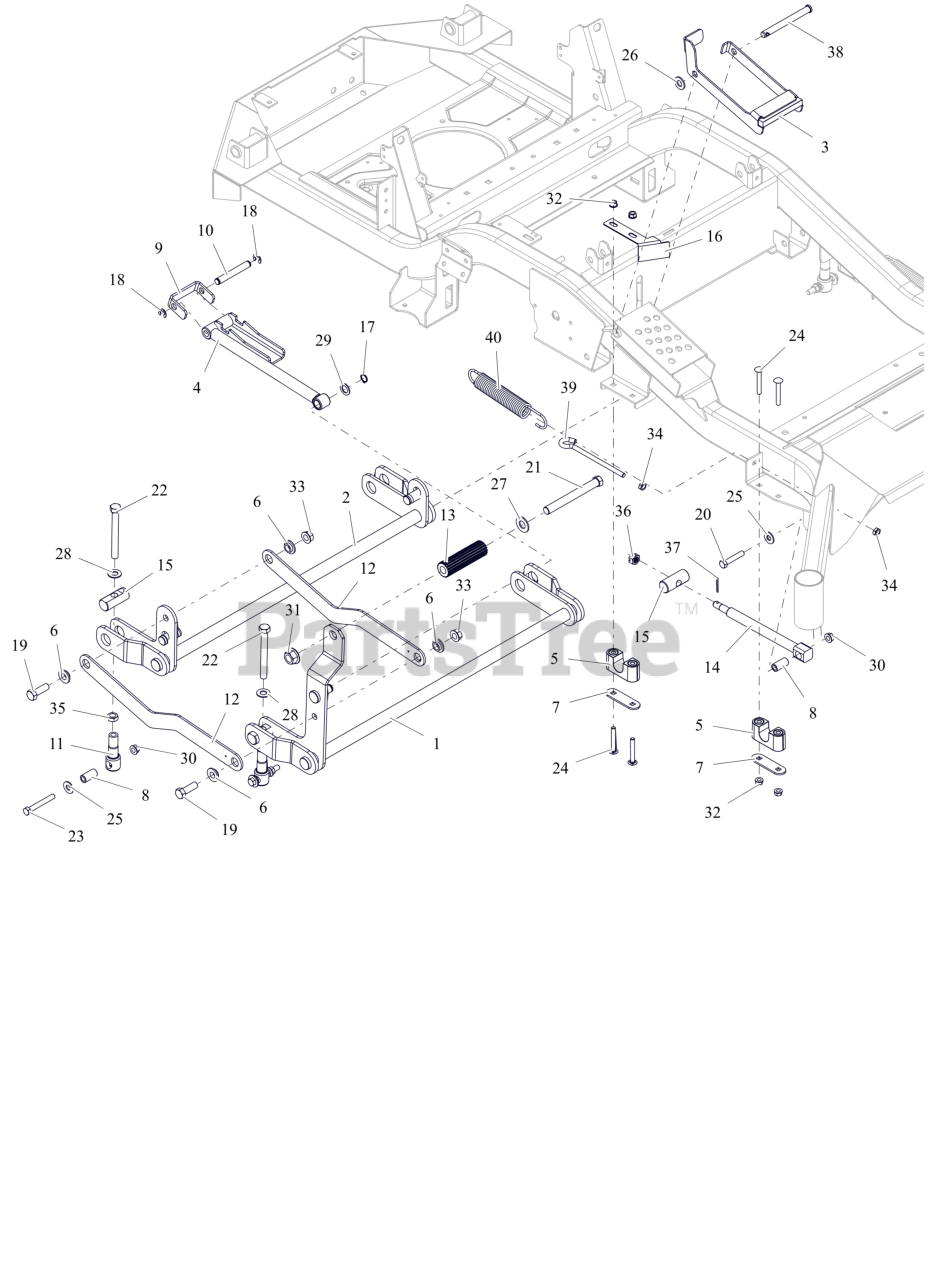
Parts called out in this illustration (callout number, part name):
1	WLDMT, FRONT DECK LIFT PIVOT
2	WLDMT, REAR DECK LIFT PIVOT
3	BRKT, HOC TRANSFER LOCK
4	WLDMT, HOC ARM
5	ASM-BUSHING, DECK LIFT
6	BSHG-FLG .515X.750X.395X1.120
7	PLATE, BEARING SUPPORT
8	SPACER, DECK LEVELING
9	BRKT, HOC LINE
10	ROD, HOC PIVOT
11	LINK, DECK LIFT FORMED
12	LINK, DECK LIFT
13	ROD, FOOT PEDAL (BLACK)
14	DRAG,LINK-HD
15	PIN, DECK LIFT
16	GUARD, STOP CE 60 (BLACK)
17	RG-RTNG-EXT .625X.050
18	RG-RTNG-EXT .500X.042 (E)
19	BLT,HEX .50-13X1.50 G5 ZCC
20	BLT,HEX .38-16X2.00 G5 ZCC
21	BLT, HEX .62-11X5.50 G5 FBP
22	BLT, HEX .50-13X4.50F G8 ZCC
23	BLT, HEX .38-16X2.75 G8 ZCC
24	BLT, RHSSN.31-18X2.25 G5 ZCC
25	WSHR,FLT .438X1.00X.083 ZCC
26	WSHR,FLT .531X1.062X.095 ZCC
27	WSHRFLT 5/8SAE CARBHARD FBP
28	WSHR, FLT .557X1.040X.102 ZCC
29	WSHR, FLT .630X1.005X.062 ZCC
30	NUT-LK-TOP-FLG .38-16 ZC120
31	NUT,FLG-TOP LK .625-11 FBP
32	NUT,LK-CTR-FLG .31-18 GF ZCC
33	NUT-LK-TOP-FLG .500-13 GF ZCC
34	NUT-JAM .375-16 G2 ZCC
35	NUT-JAM .500-13 G2 ZCC
36	NUT-SL .50-13
37	PIN,CTR.12X1.25EXTPRSQCT ZC120
38	PIN-SLIC .50X4.97X4.55 -ZCC
39	BOLT,.38-16 X 5.25-.62 DIA EYE
40	SG-TENS .162X1.25X8.25 WLD 25
